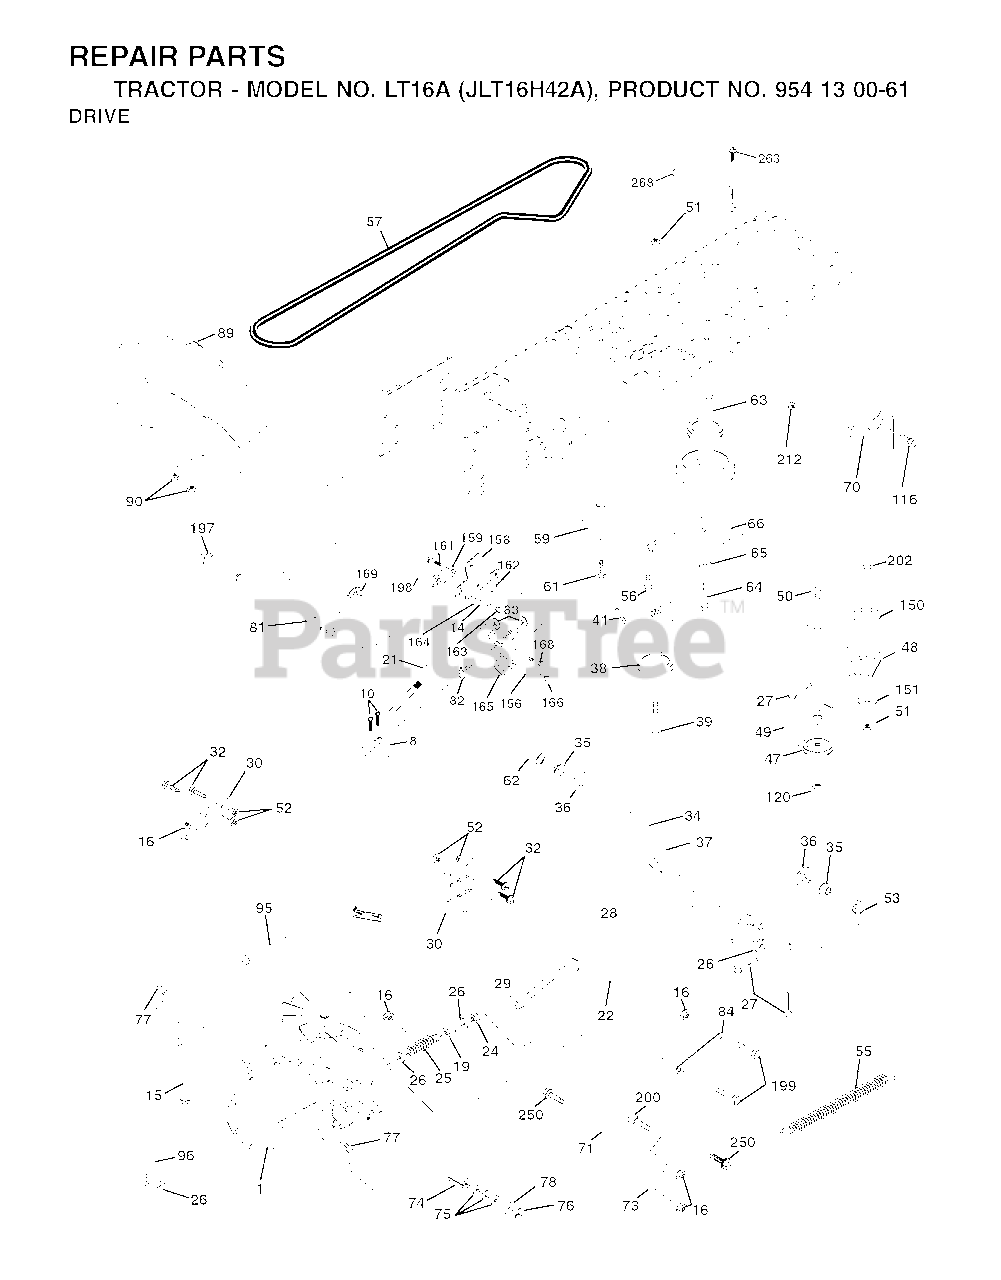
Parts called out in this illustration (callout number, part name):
8	ROD SHIFT FENDER ADJUST STLT
10	PIN COTTER
14	LOCKWASHER
15	BOLT HEX 5/16-18 GR 5
16	NUT.71038.31-18.HEX.NYLOCK
19	NUT
21	PISTOL KNOB
22	ROD BRAKE HYDRO
24	NUT
25	SPRING ROD LT
27	COTTER PIN
28	ROD, PARKING BRAKE
29	PLUNGER CAP
30	BRKT, TRNSXLE MNT 20"
32	BOLT
34	SHAFT, FOOT PEDAL
35	BEARING.NYLON
36	WASHER LT
37	DRIVE PIN
38	PULLEY IDLER COMPOSITE
39	BOLT
41	KEEPER, BELT IDLER
47	IDLER PULLEY
48	BELLCRANK, CLUTCH
49	RETAIN BELT
50	BOLT.3/8-16X1.50
51	LOCKNUT
52	LOCKNUT
53	LINK, CLUTCH LT
55	SPRING, RETURN LT
56	SCREW.3/8-16
57	DRIVE BELT, LTH & YTH TRACTORS
59	KEEPER, BELT CENTER
61	SCREW 3/8-16X.875
62	PEDAL COVER T
64	BOLT
65	LOCKWASHER
66	KEEPER BELT ENGINE
71	STRAP TORQUE LH HYDRO
73	STRAP TORQUE RH HYDRO
74	SPACER AXLE
76	E-RING LT
77	SQUARE KEY
81	SHAFT ASM CROSS TAPERED
82	SHIFT SPRING
83	WASHER
84	LINK TRANSAXLE
95	CONTROL ASM. BYPASS HYDRO
96	RETAINER M
116	BOLT D
120	NUT LOCK FLG 3/8-16 UNC
150	SPACER, RETAINER
151	WASHER 12/32X2X10GA
156	WASHER.SRRTD.5/16
158	BRACKET
159	HUB
161	BOLT
162	NUT.CROWNLOCK.1/4
163	BOLT
165	RP BRACKET
168	BOLT.SHOULDER.5/16-18X
169	PLATE.FASTENING.CROSS.SHAFT
197	NYLINER SNAP 5/8" ID
198	WASHER.NYL.7/8IDX.105"HYD CR
199	BOLT SHOULDER 5/16-18 UNC
200	BOLT
202	BOLT
212	NUT
250	SCREW 3/8-16X3/4
263	SCREW, 3/8-16X3/4
